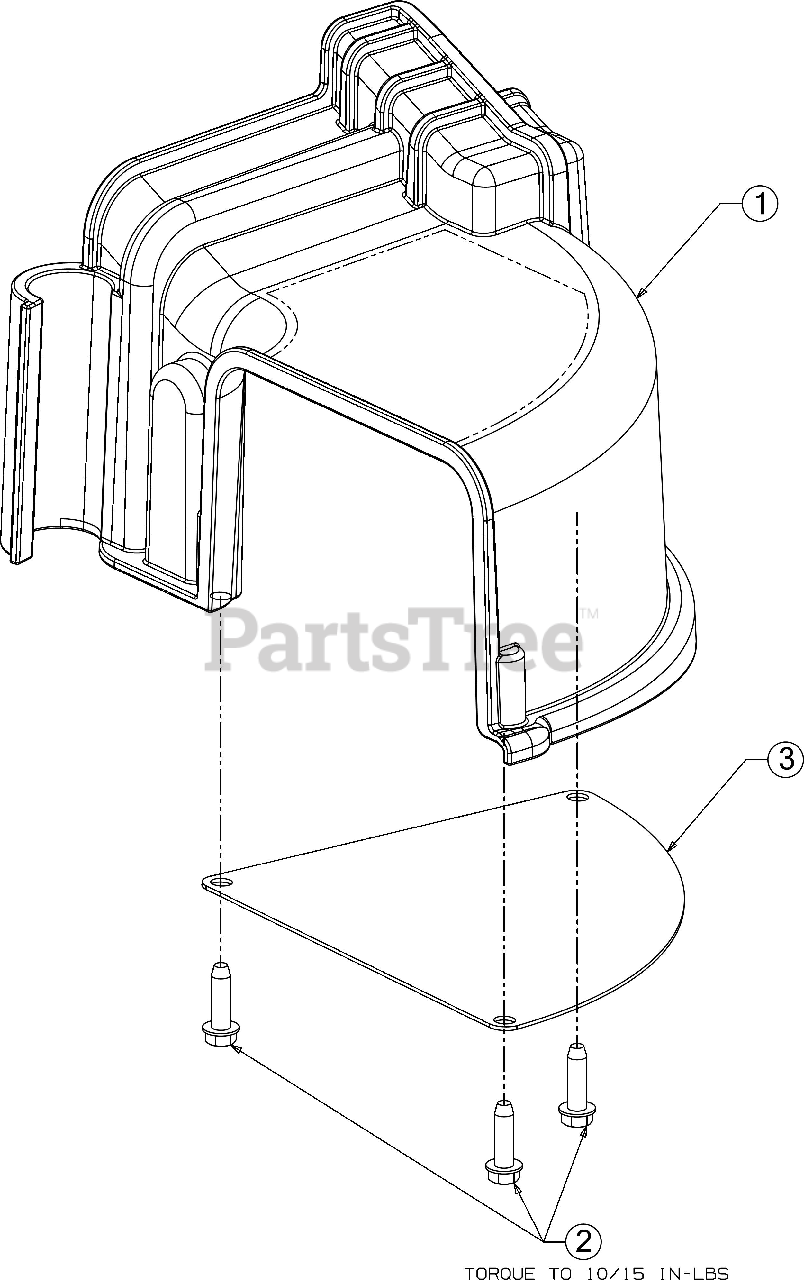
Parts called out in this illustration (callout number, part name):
1	90 DEGREE DISCHARGE CHUTE ASSEMBLY
2	SCREW #12-16 .75
3	DISCHARGE CHUTE BRACKET
